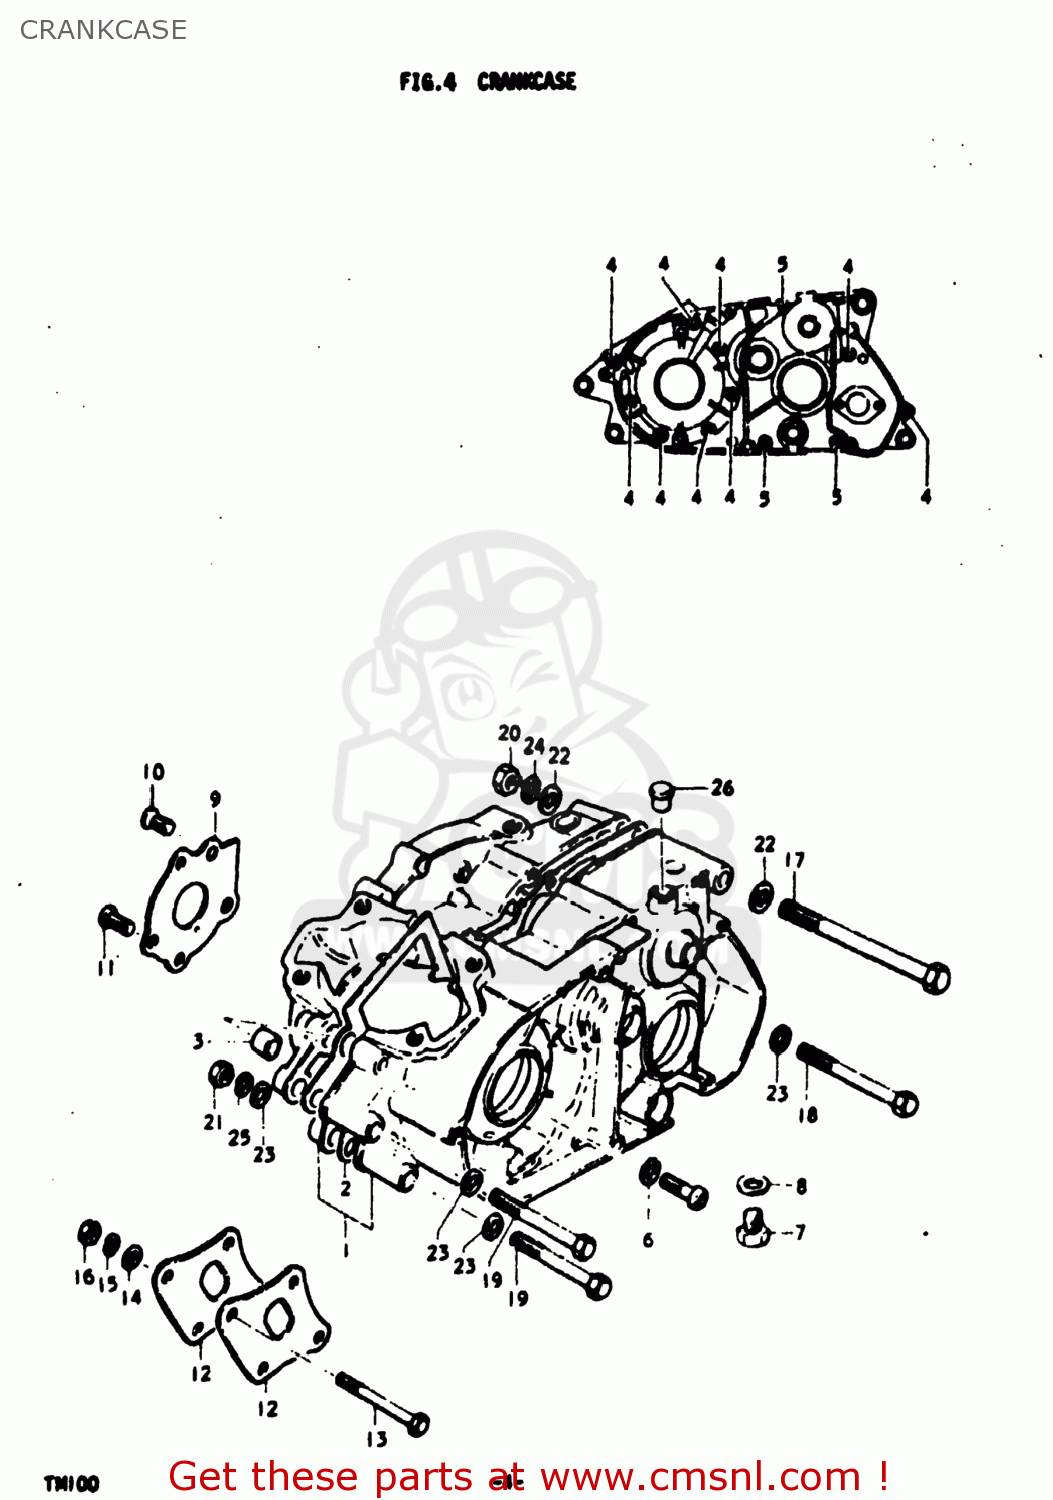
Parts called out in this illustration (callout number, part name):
1	CRANKCASE SET
2	GASKET,CRANKCASE (MCA)
3	PIN
4	SCREW (6X45)
5	SCREW
6	WASHER 6MM
7	PLUG
8	GASKET(10X14X3.6) (NAS)
9	PLATE,OIL RESERVOIR
10	SCREW
11	CROSS HEAD SCREW
12	PLATE,ENGINE MOUNTING
13	BOLT
14	WASHER
15	LOCK WASHER
16	NUT
17	BOLT
18	HEXAGON BOLT 8X80
19	BOLT
20	NUT
21	NUT
22	WASHER
23	WASHER
24	LOCK WASHER
25	LOCK WASHER
26	CAP(OD:14)
